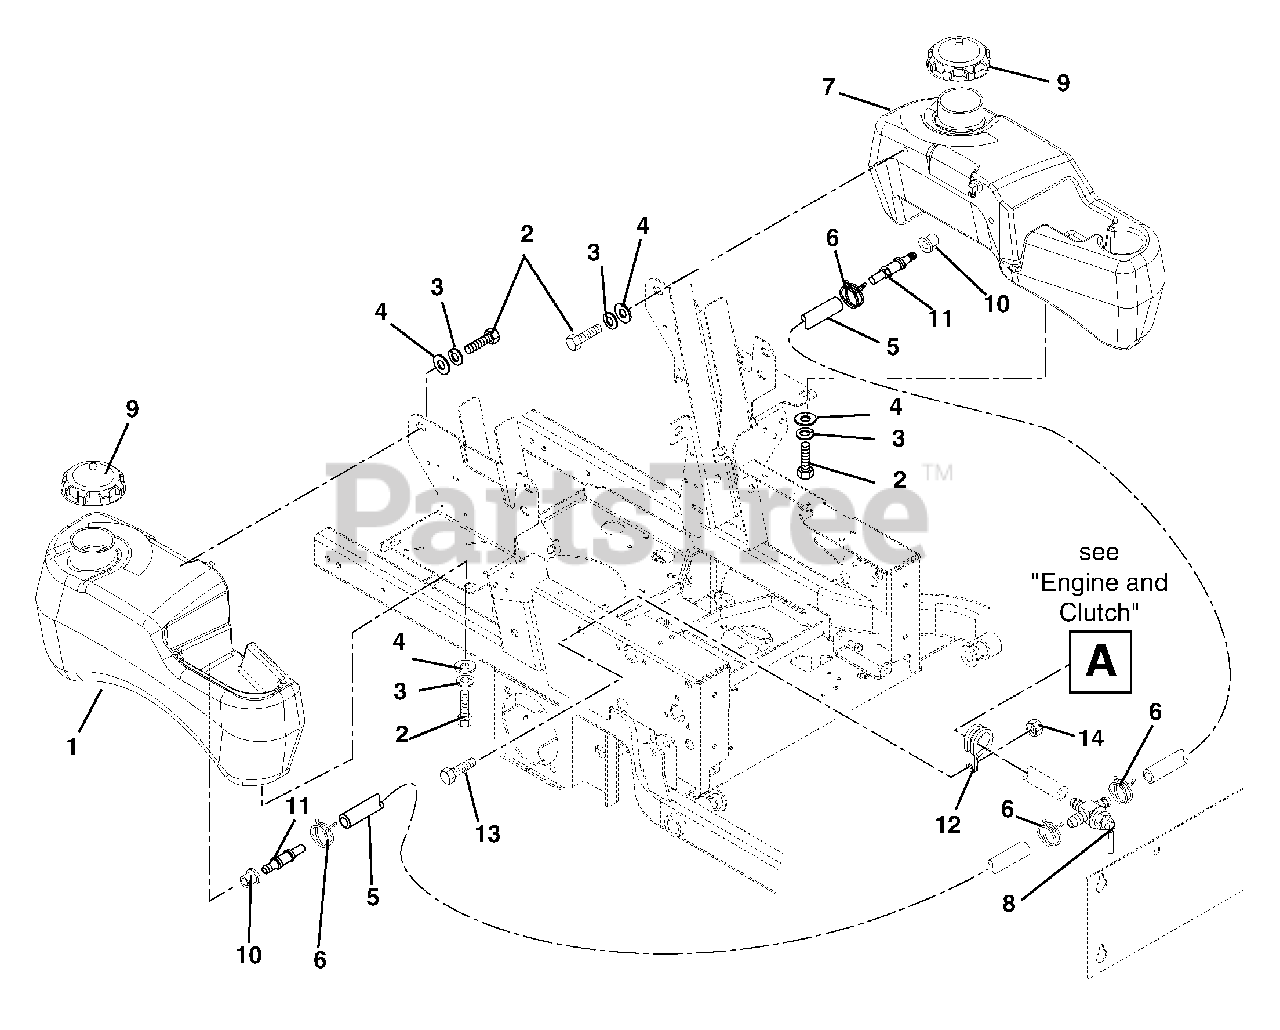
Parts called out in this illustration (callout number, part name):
1	Tank, Gas - Right Hand
2	Bolt, Hex .31-18 x .75 Grade 5
3	Washer, Locking .31 x .078
4	Washer, Flat Steel .38 x .875 x .083
5	Gas Line, Bulk .25" ID
6	Hose, Clamp
7	Tank, Gas - Left Hand
8	Valve, Fuel
9	Cap, Gas
10	Bushing
11	Fuel Tank Fitting
12	Clamp, Cushioned Steel (054, 055)
13	Bolt, Hex .38-16 x 1.00 Grade 5 (054, 055)
14	Nut, Locking Top Flange .38-16 (054, 055)
